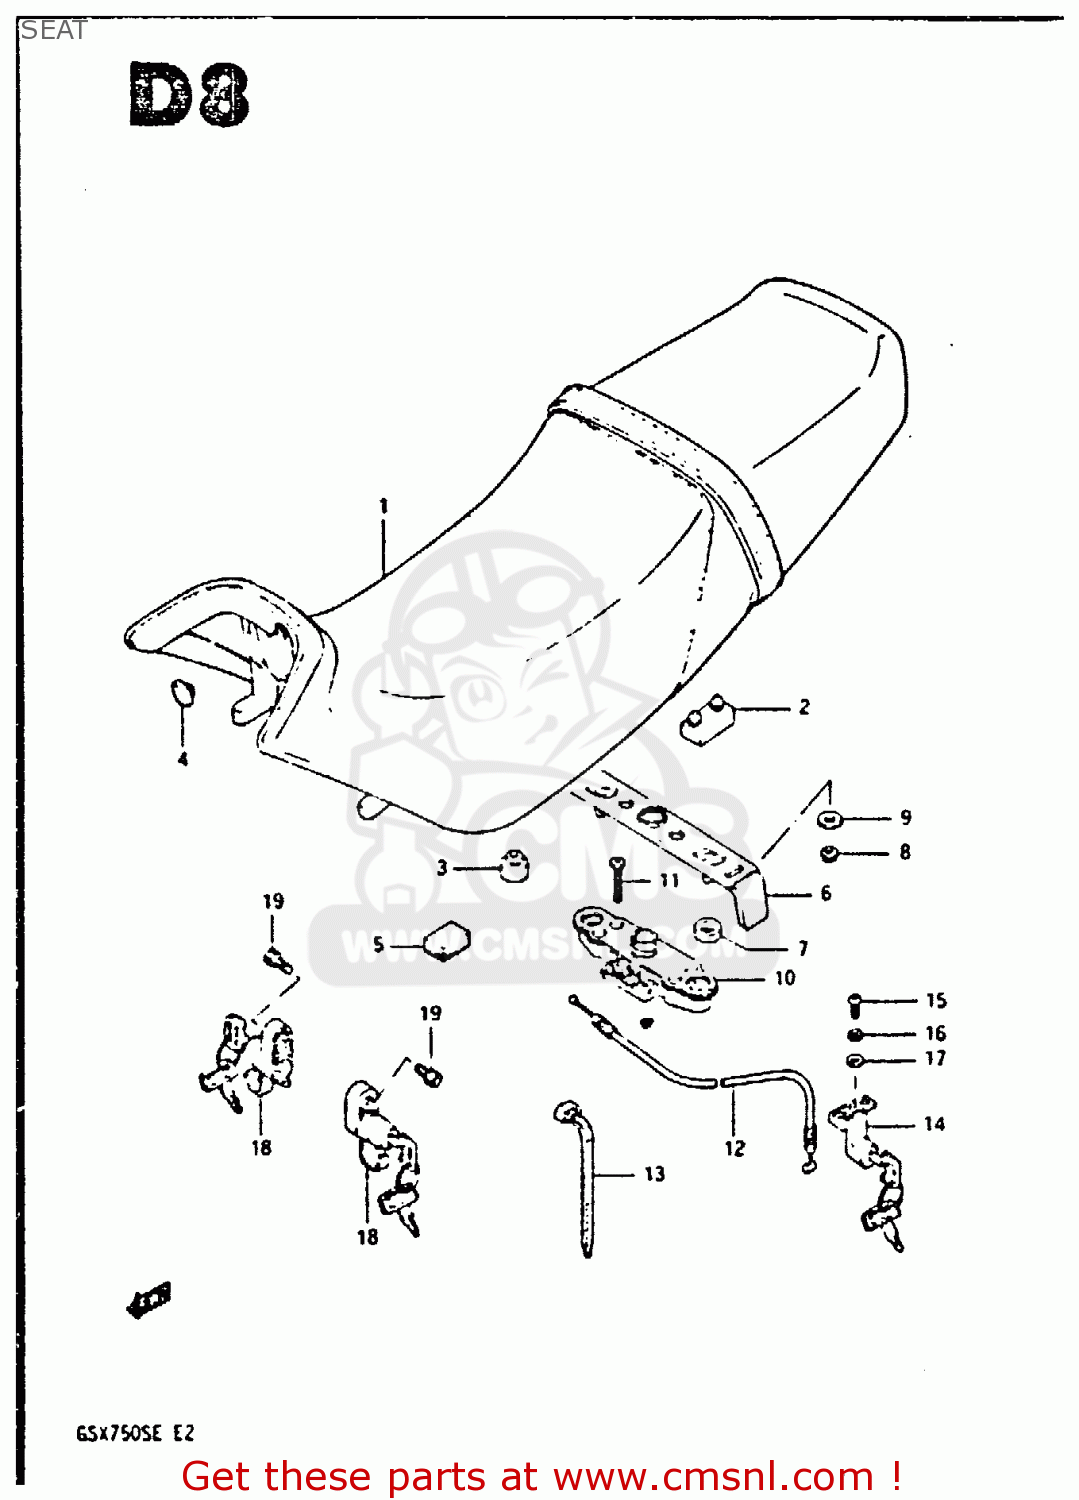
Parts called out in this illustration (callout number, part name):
1	SEAT ASSY
2	CUSHION,SEAT(40X20X15)
3	CUSHION
4	CUSHION
5	CUSHION,TOOL(40X30X15)
6	STRIKER, SEAT LOCK
7	CUSHION,STRIKER
8	NUT
9	WASHER (6.5X24X1.6)
10	LOCK ASSY,SEAT STRIKER
11	SCREW,6X30
12	CABLE,SEAT LOCK
13	CLAMP(L:165)
14	LOCK, SEAT
15	BOLT
16	WASHER,LOCK
17	WASHER,5MM
18	LOCK SET
19	BOLT
